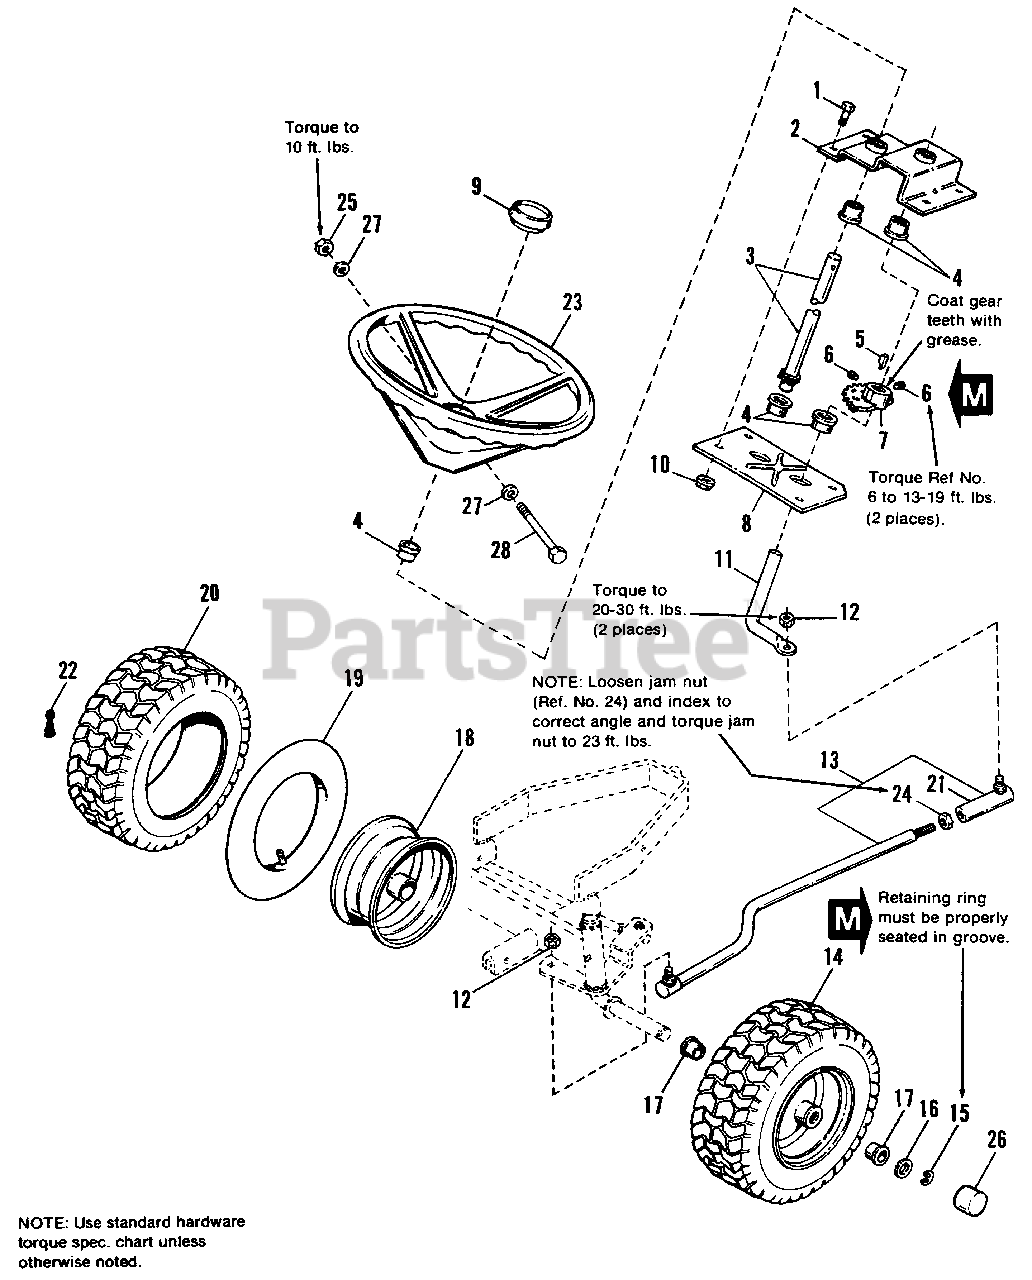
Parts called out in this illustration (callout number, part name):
1	CAPSCREW, Hex Hd., 5/16-18 x 3/4
2	PLATE, Steering
3	SHAFT ASSY., Steering
6	SETSCREW, 5/16-18 x 1/2
7	GEAR, Steering
8	PLATE, Base, Steering
9	CAP, Steering Wheel
10	LOCKNUT, Hex, Flange, 5/16-18
11	ROD, Steering
12	NUT, Special, 3/8-24
13	LINK ASSY., Drag (Incl. Ref. No. 21 & 24)
14	WHEEL & TIRE ASSY.
18	WHEEL ASSY. 15 x 6.00-6
19	TUBE, 4.10/3.50-6 (For Service Only)
20	TIRE, (Carlisle)
21	BALL JOINT ASSY.
22	VALVE STEM & CAP
23	WHEEL, Steering, Bolt Mounted
24	NUT, Jam 3/8-24
25	LOCKNUT, Hex, 5/16-18
26	HUB CAP, Threaded
27	WASHER, Plain
28	BOLT, 5/16-18 x 3-1/2
